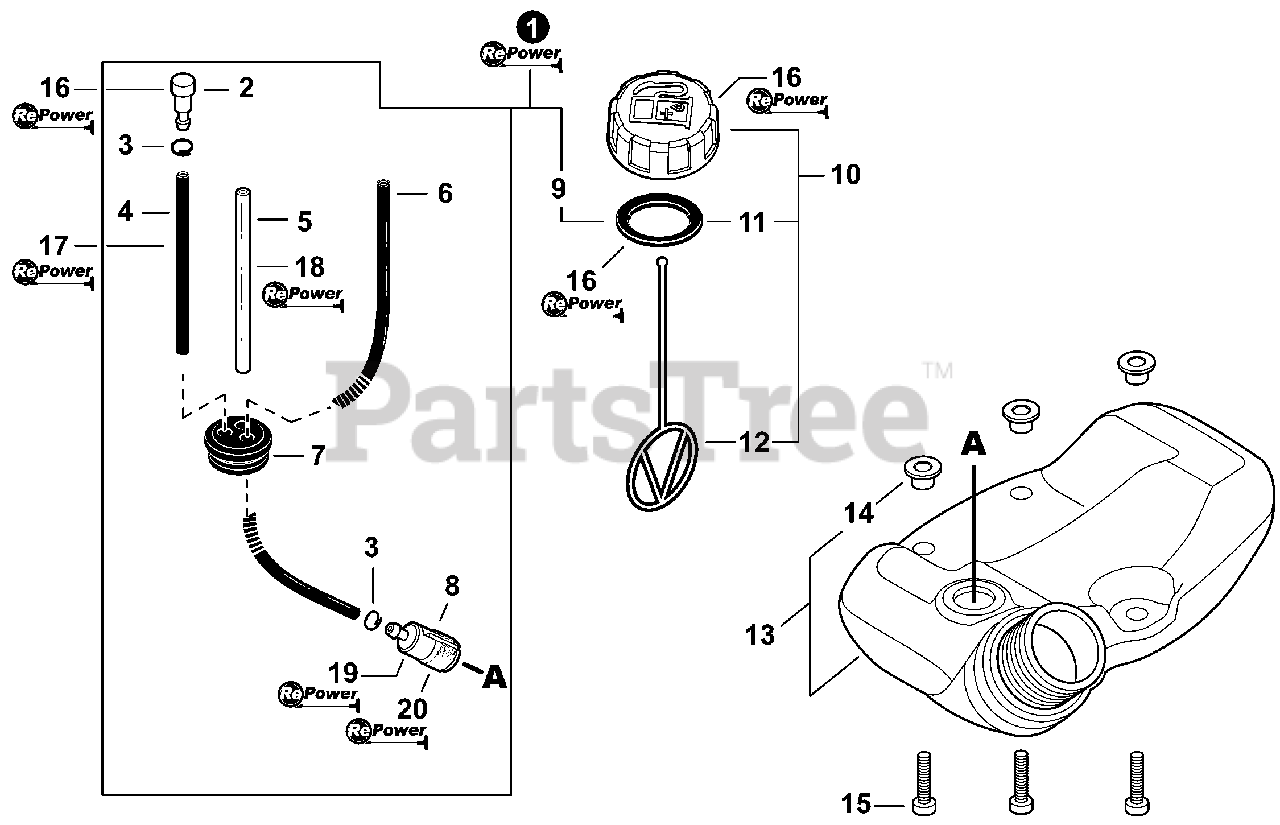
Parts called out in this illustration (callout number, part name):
1	FUEL SYSTEM KIT - REPOWER
2	VENT ASSY
3	CLIP 6MM
4	PIPE, FUEL 3×5×90 BLACK
5	PIPE, FUEL 3×6×80 CLEAR
6	PIPE, FUEL
7	GROMMET, FUEL
8	FILTER, FUEL
9	GASKET, FUEL CAP
10	CAP ASSY, FUEL
11	GASKET, FUEL CAP
12	CONNECTOR, CAP L= 123
13	TANK ASSY, FUEL
14	COLLAR 5
15	BOLT, TORX 5×20
16	CAP/VENT KIT - REPOWER
17	PIPE, BULK - REPOWER 3×5mm BLACK
18	PIPE, BULK - REPOWER 3×6mm CLEAR
19	TUNE-UP KIT - REPOWER
20	FILTER KIT - REPOWER
